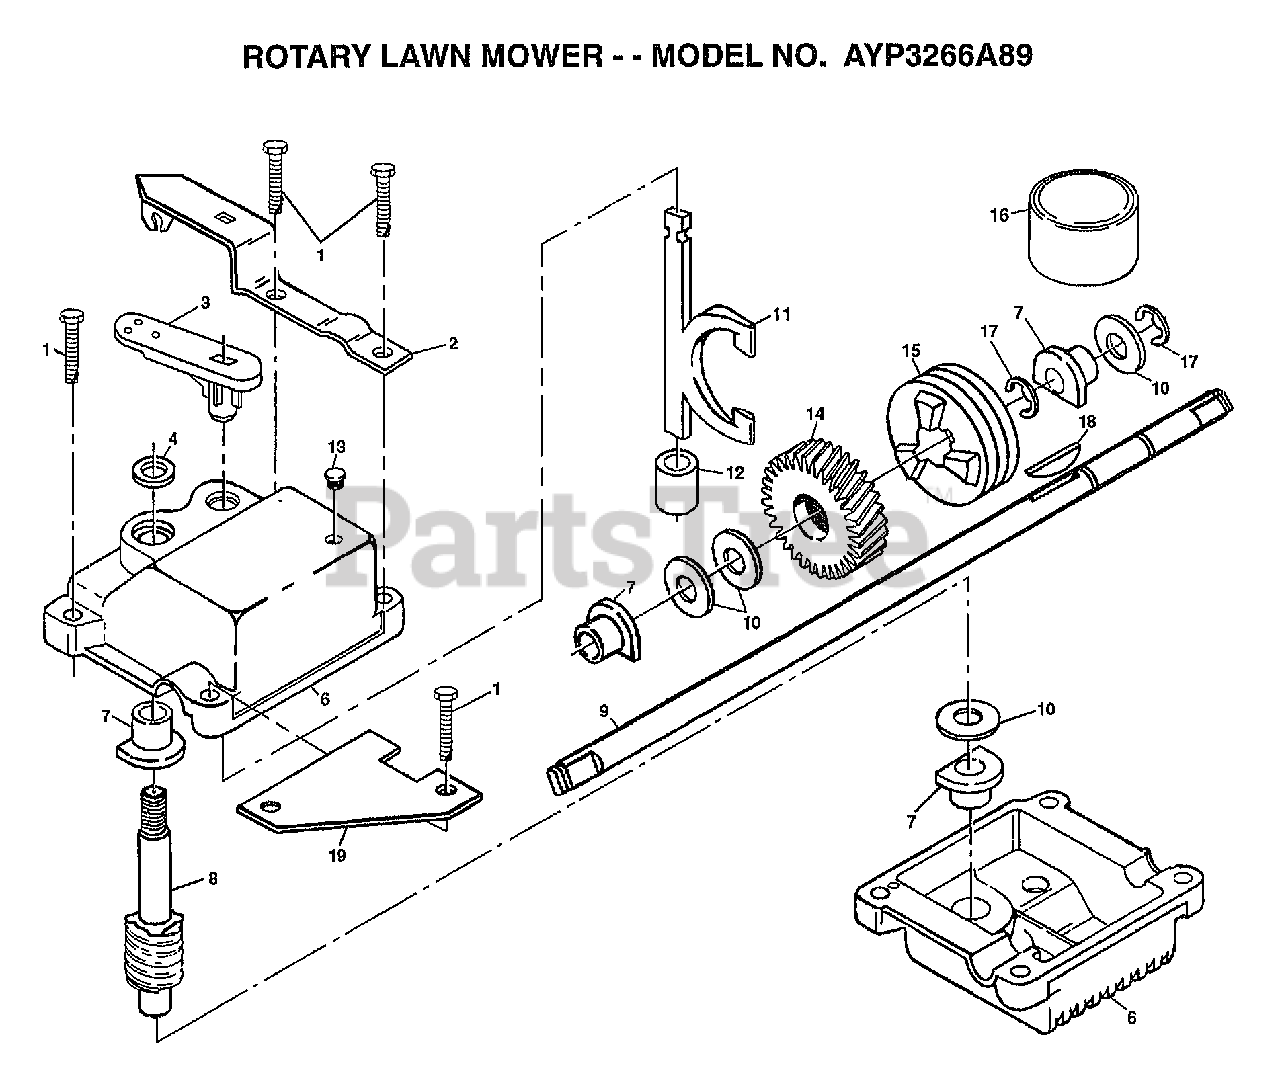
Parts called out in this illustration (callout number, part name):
1	SCREW.1/4-20
2	BRACKET.GEARCASE
3	SHIFTER
4	SEAL
6	KIT GEARCASE HALV
7	BEARING
8	SHAFT.WORM
9	SHAFT.DRIVE.SD
10	THRUST WASHER
11	CLUTCH YOKE
12	BUSHING.GEAR BOX
13	PLUG PM
14	GEAR.HELICAL
15	CLUTCH JAW
17	RING T
18	HI PRO KEY
